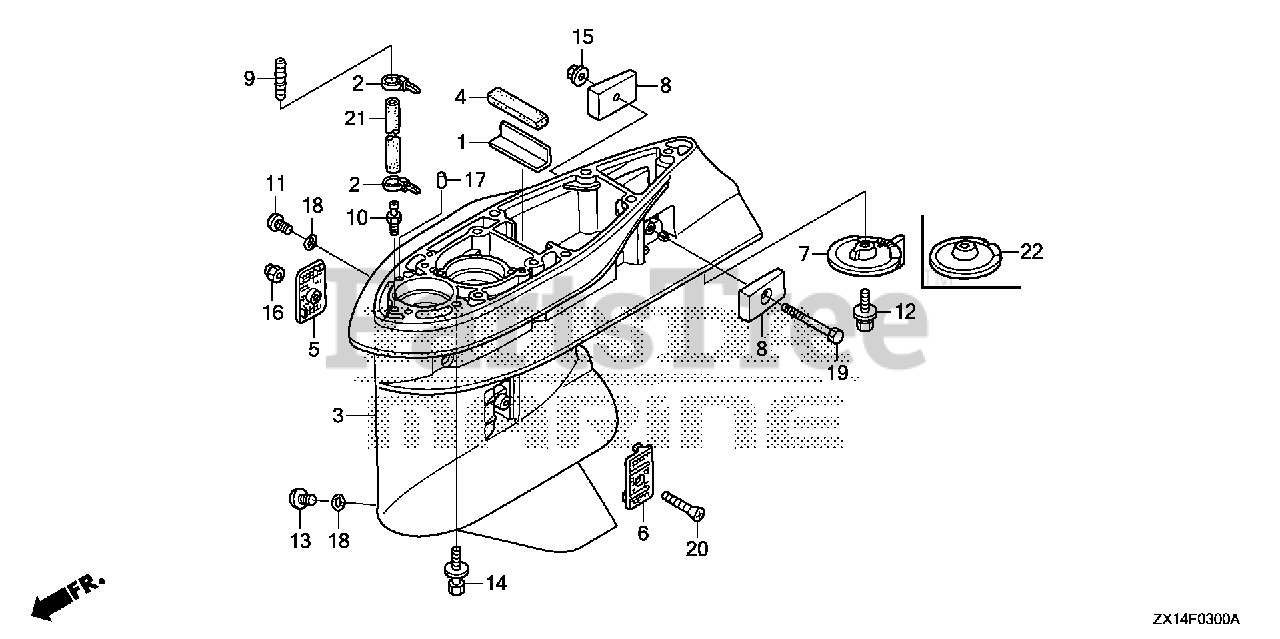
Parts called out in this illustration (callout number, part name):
1	PLATE, RUBBER SETTING
2	BAND, WIRE
3	CASE, GEAR *NH282MU* (OYSTER SILVER METALLIC-U)
4	GROMMET, GEAR CASE
5	SCREEN, R. WATER
6	SCREEN, L. WATER
7	TAB, TRIM *NH282MU* (OYSTER SILVER METALLIC-U)
8	METAL, ANODE
9	END, NIPPLE
10	NIPPLE, SENSOR
11	BOLT, OIL CHECK
12	BOLT-WASHER (10X32)
13	BOLT, DRAIN PLUG
14	BOLT-WASHER (10X40)
15	NUT, SELF-LOCK (6MM)
16	NUT, SELF-LOCK (5MM)
17	PIN, DOWEL (6X10)
18	O-RING (6.9X1.45)
19	BOLT, HEX. (6X50)
20	SCREW, OVAL (5X50)
21	BULK HOSE, VACUUM (5X3000) (5X250)
